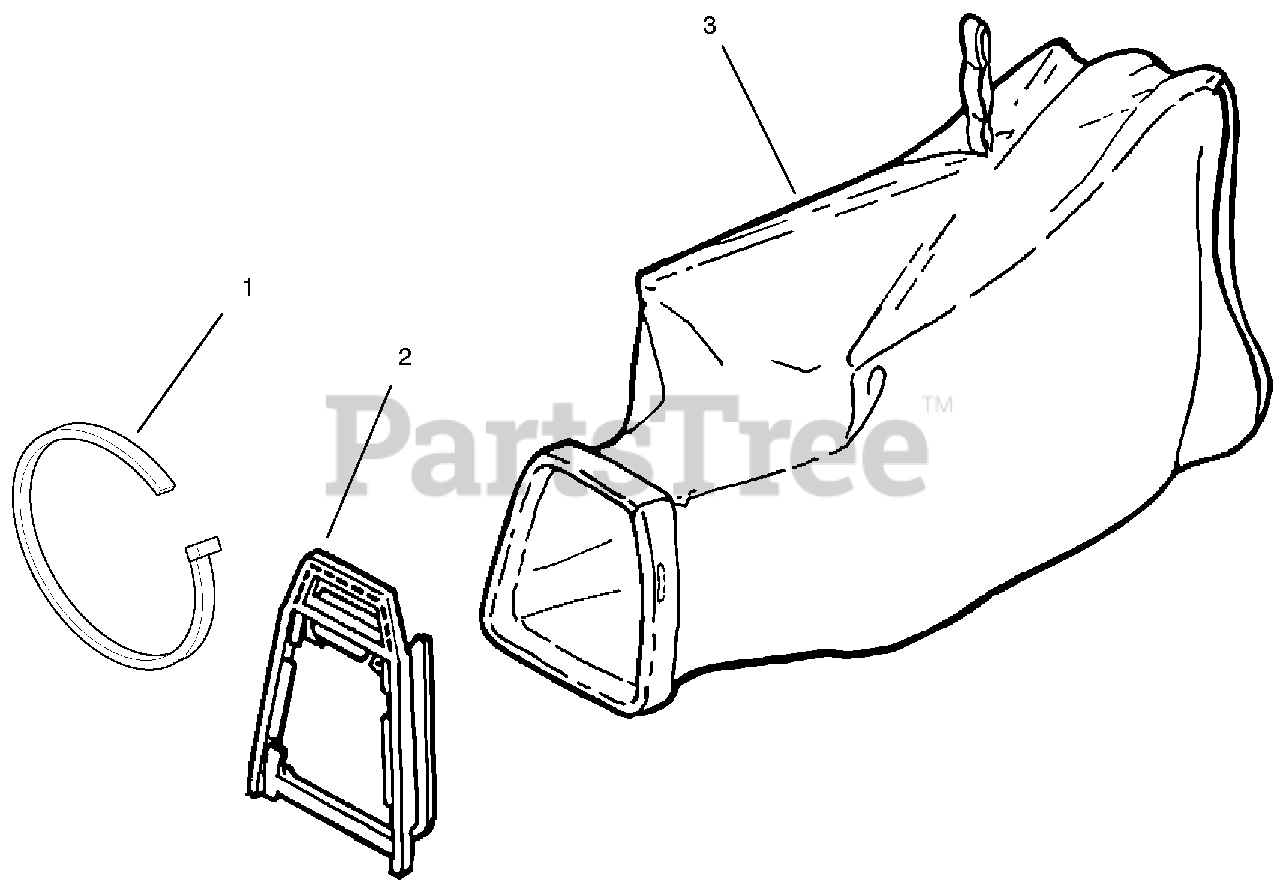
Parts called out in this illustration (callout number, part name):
1	Strap-Tie
2	Adaptor-Chute
3	Bag-Leaf (Incl. Ref. #1 & 2)
